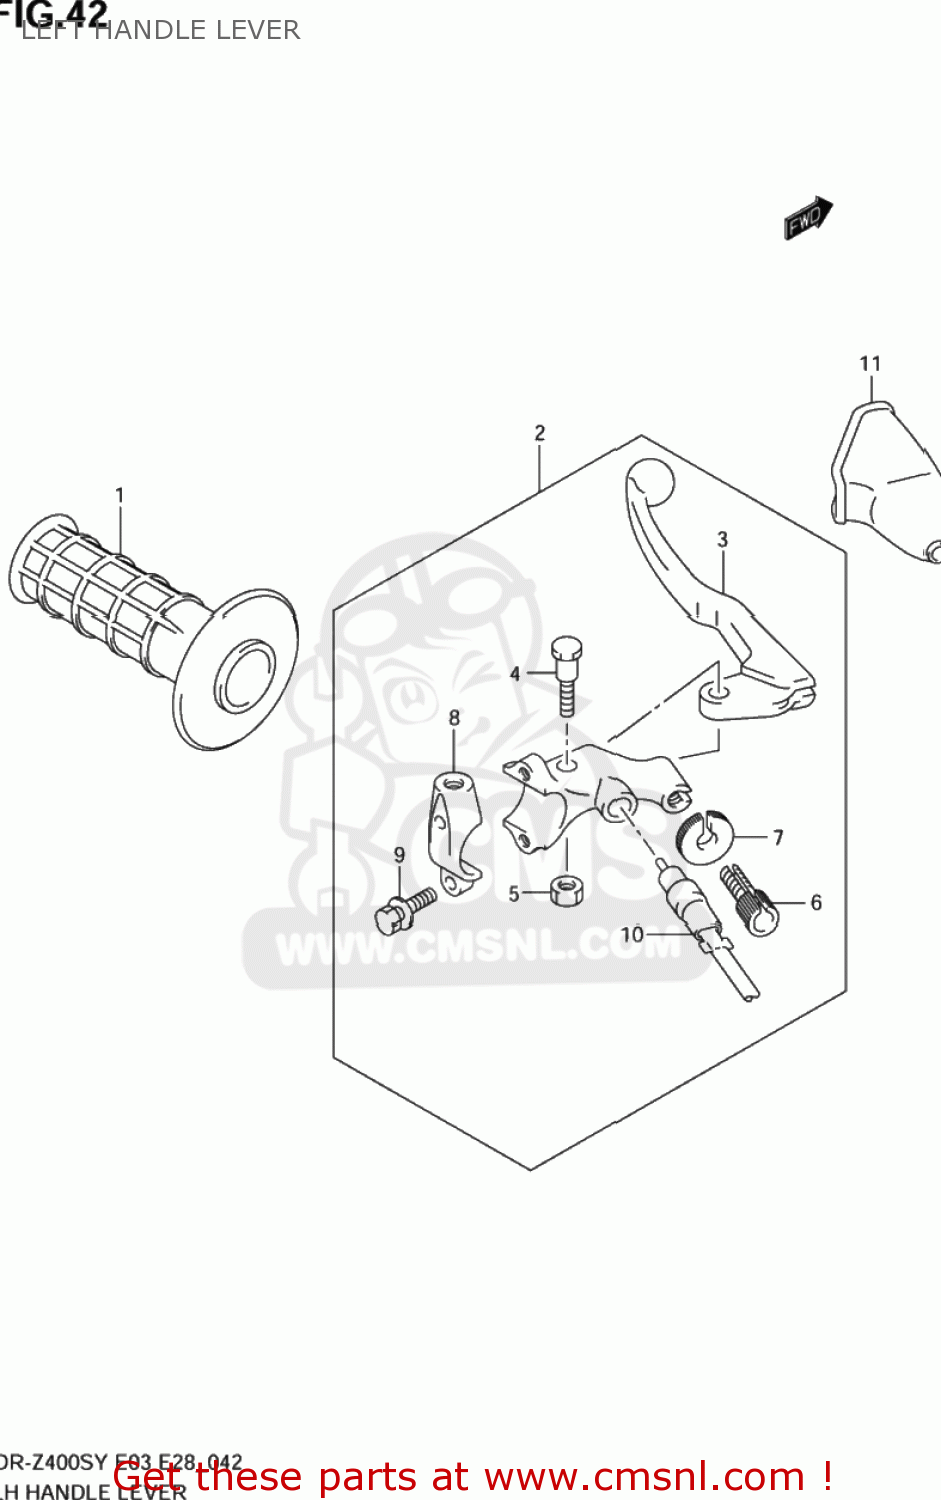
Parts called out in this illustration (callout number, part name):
1	GRIP,L
2	LEVER ASSEMBLY,CLUTCH
3	LEVER,CLUTCH
4	BOLT,LEVER PIVOT
5	NUT 6MM
6	ADJUSTER,WIRE
7	NUT,LOCK
8	BRACKET,HOLDER
9	BOLT,BRACKET
10	SWITCH ASSEMBLY,CLUTCH
11	COVER,CLUTCH CABLE DUST
